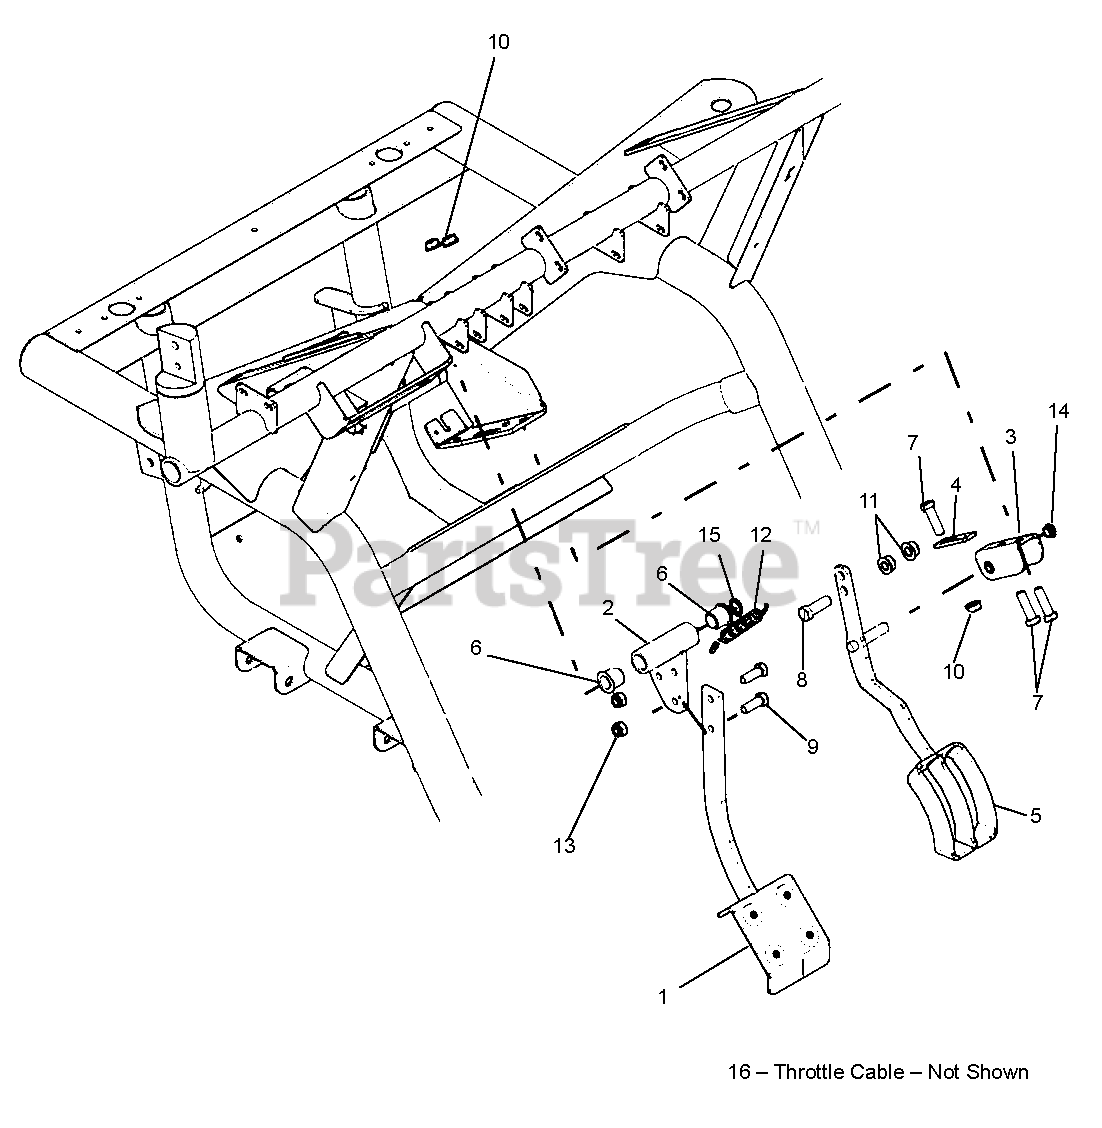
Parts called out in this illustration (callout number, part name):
1	BRAKE PEDAL ASSEMBLY
2	BRAKE PEDAL PIVOT WELDMENT
3	GAS PEDAL MOUNT
4	GAS PEDAL ADJUSTMENT PLATE
5	WELDMENT, GAS PEDAL
6	BUSHING, 3/4OD X 5/8ID X 3/4 FLG HD
7	BOLT, HEX .31-18 X 1.25 GR5 YWZC
8	BOLT, HEX 3/8-16 X 1 1/4 GR5 YWZC
9	BOLT, HEX .31-18 X 1.00 GR5 YWZC
10	NUT, LOCKING TOP FLANGE .31-18 YWZC
11	NUT, LOCKING TOP FLANGE .38-16 YWZC
12	SPRING, EXTENSION .5OD .075W 2.75LG
13	NUT, LOCKING NYLON .312-18 YWZC
14	BUSHING NYLON 3/8 ID (SNAP IN)
15	SNAP RING, .625 X .035 EXT
